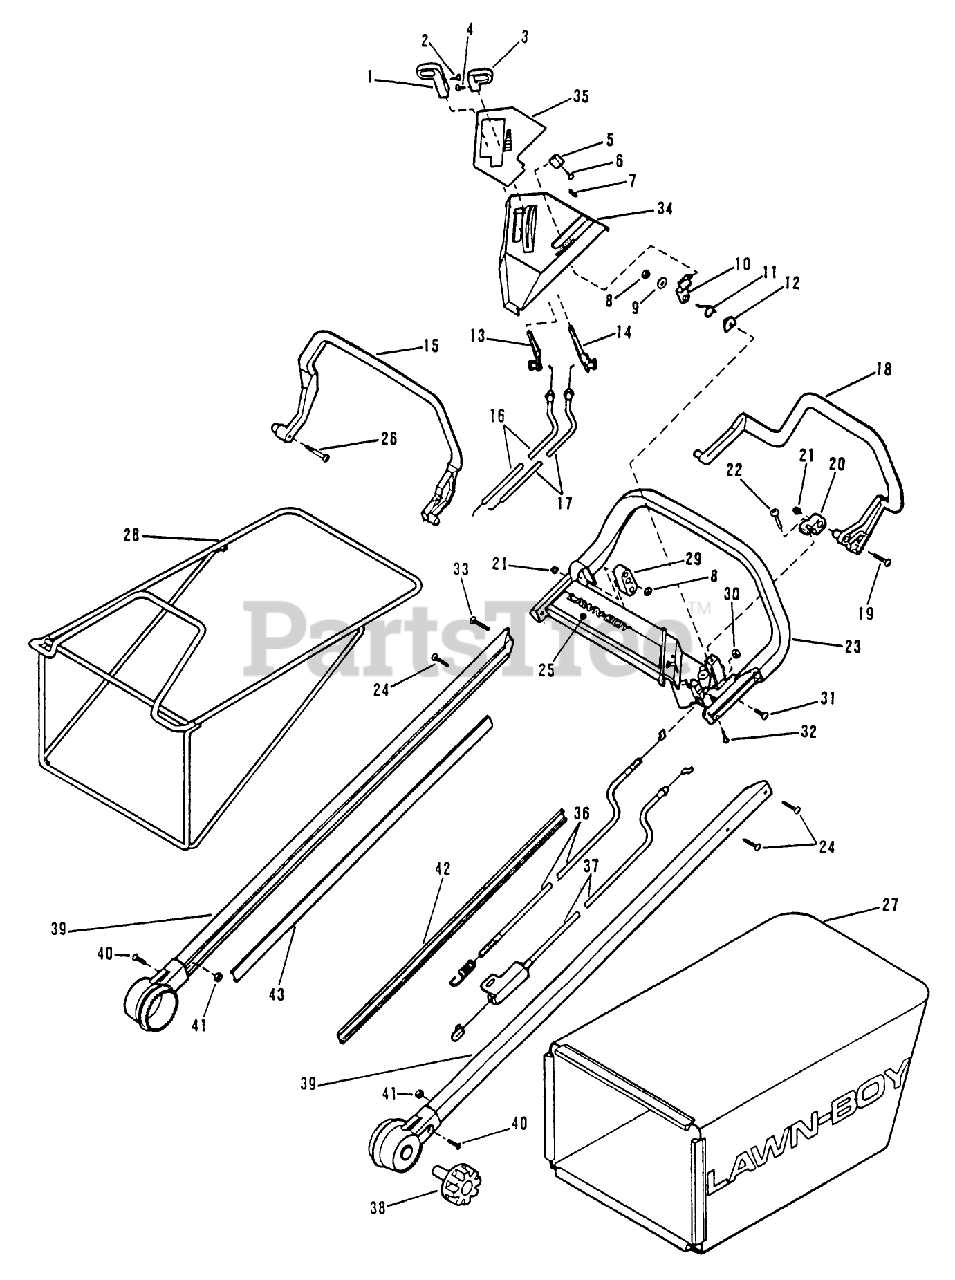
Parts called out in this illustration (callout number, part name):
1	KNOB & SCREW AY
8	LOCKNUT E
10	BBC LATCH LB
11	SPRING
16	CABLE AY. WESCON
17	CABLE
18	BAIL-S.P. *
20	PIVOT BAIL PL
21	LOCKNUT FLAN
24	SCREW
29	BLOCK BAIL PL
31	SCREW-CROSS RECESS
33	SCREW-TRUSS
36	CABLE AY
37	CABLE AY WESC
38	KNOB-HDLE MT.ASM*B
39	HANDLE SHAFT AY
41	LOCKNUT FLAN
42	INSERT - HANDLE
